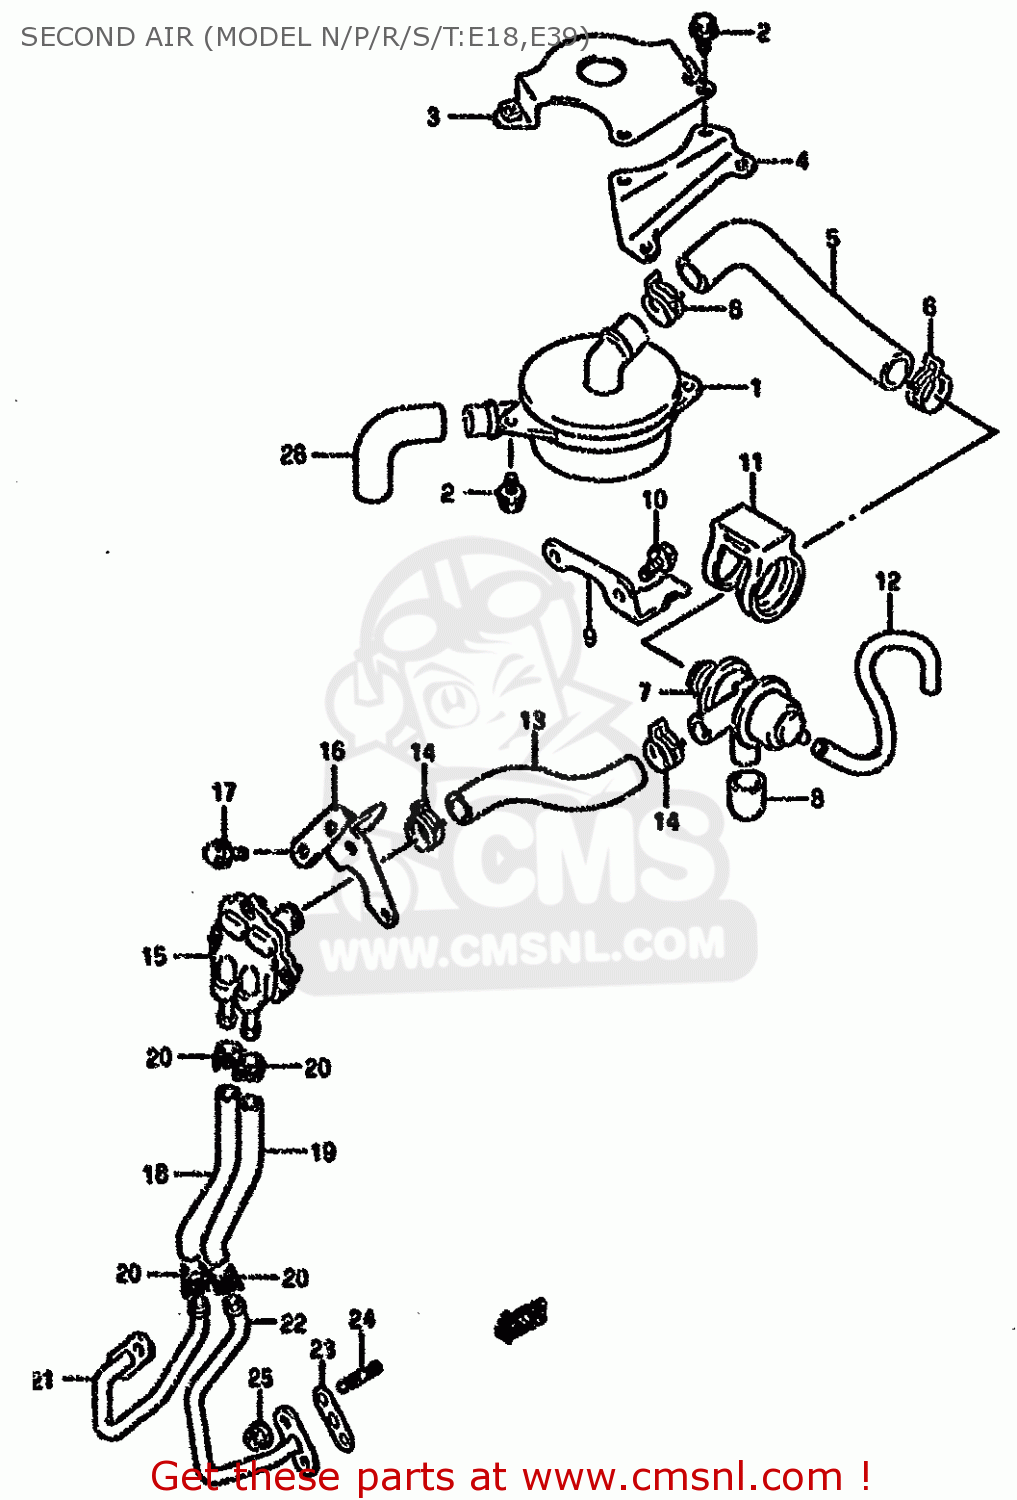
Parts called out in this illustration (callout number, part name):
1	CLEANER ASSEMBLY,SECOND AIR
2	BOLT
3	BRACKET,2ND AIR CLEANER
4	BRACKET,2ND AIR CLNR SUPPORT
5	HOSE,2ND AIR CLEANER
6	CLIP
7	VALVE ASSY,2ND AIR SWITCHING
8	CAP,SWITCHING VALVE
9	BRACKET, SWITCHING VALVE
10	BOLT
11	CUSHION,2ND AIR VALVE
12	HOSE (4.5X8.5X300)
13	HOSE,2ND AIR
14	CLIP
15	VALVE ASSY,2ND AIR REED
16	BRACKET, REED VALVE
17	BOLT
18	HOSE,2ND AIR REED VALVE,R
19	HOSE,REED VALVE L
20	CLIP
21	PIPE,2ND AIR,R
22	PIPE,2ND AIR,L
23	GASKET,SECOND AIR PIPE (N (NAS)
24	STUD 6X16
25	NUT
26	HOSE,SECOND AIR NO.2
